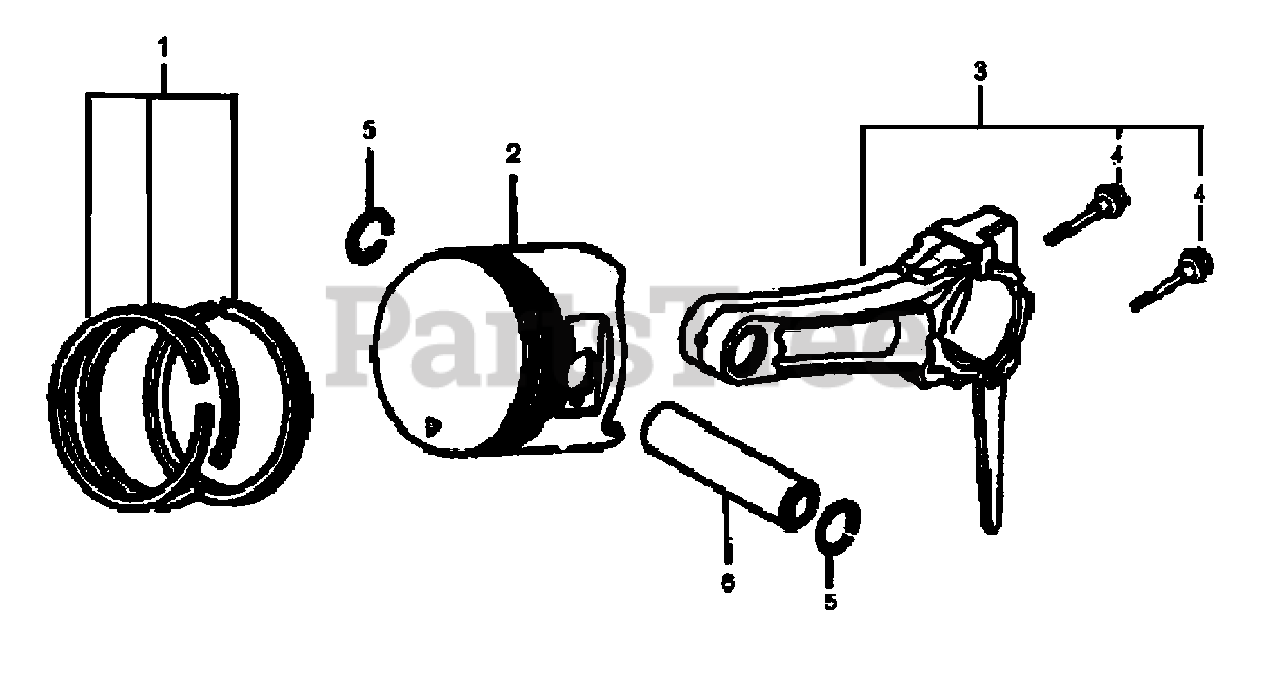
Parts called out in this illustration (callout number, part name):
1	RING SET, PISTON
3	ROD ASSY, CONNECTING
4	BOLT, CONNECTING ROD
5	RETAINER, PISTON PIN
6	PIN, PISTON
